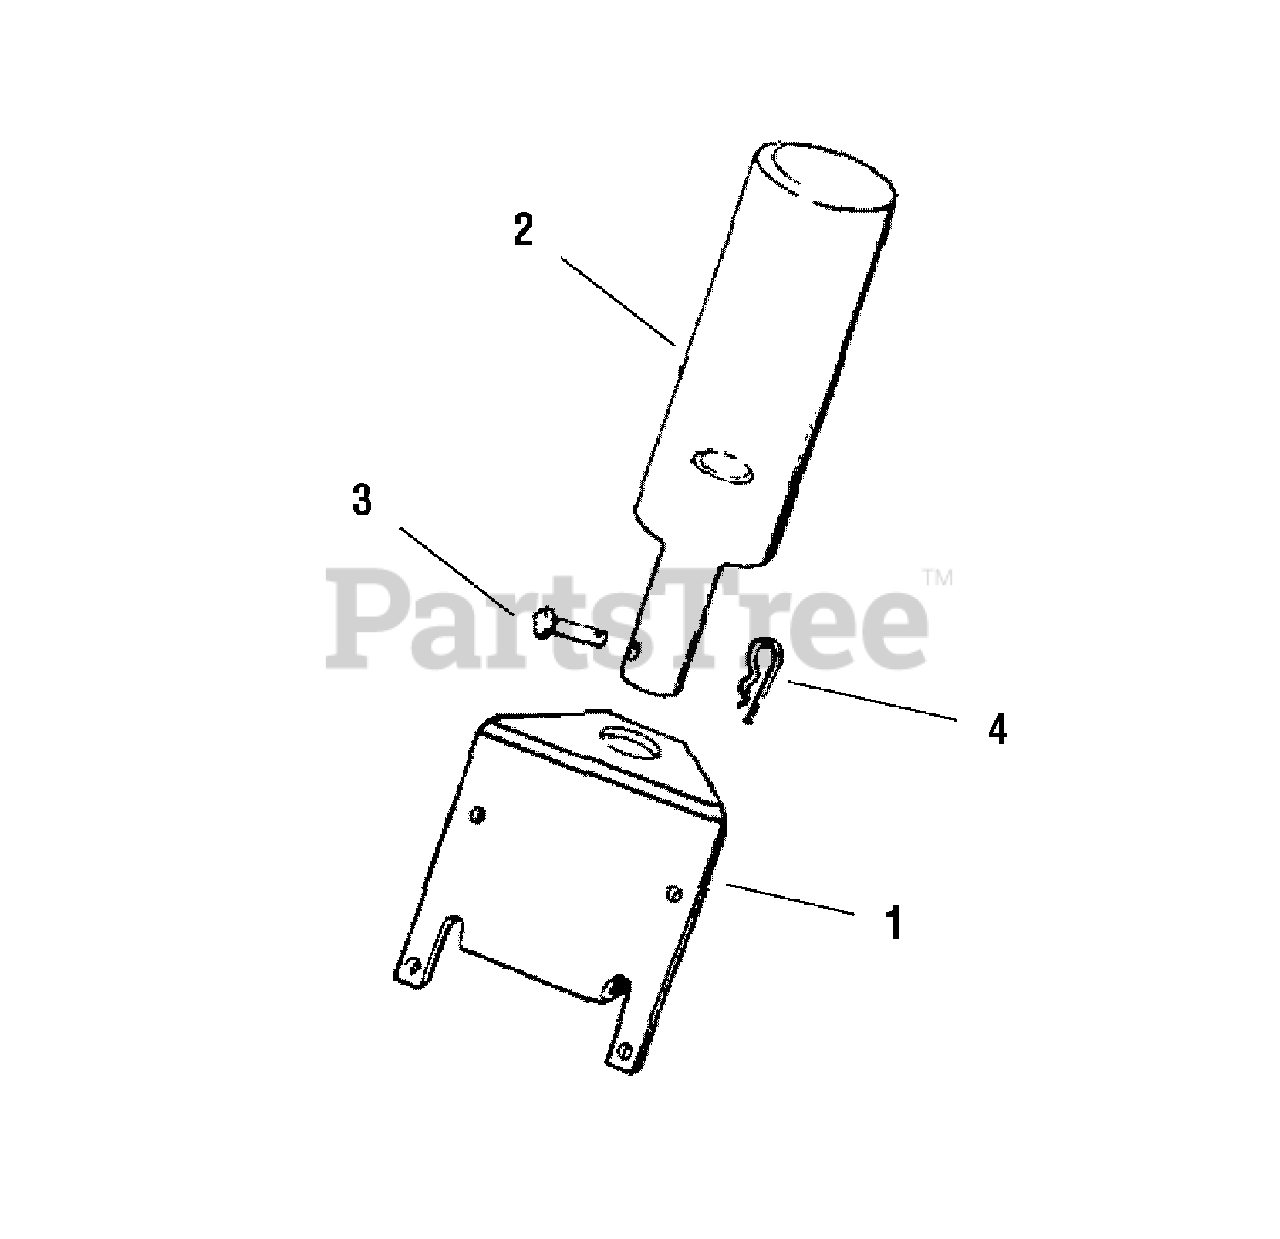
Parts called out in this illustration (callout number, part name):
A	BRACKET, Weight
B	WEIGHT ASSSEMBLY
C	PIN
D	CLIP, Spring
